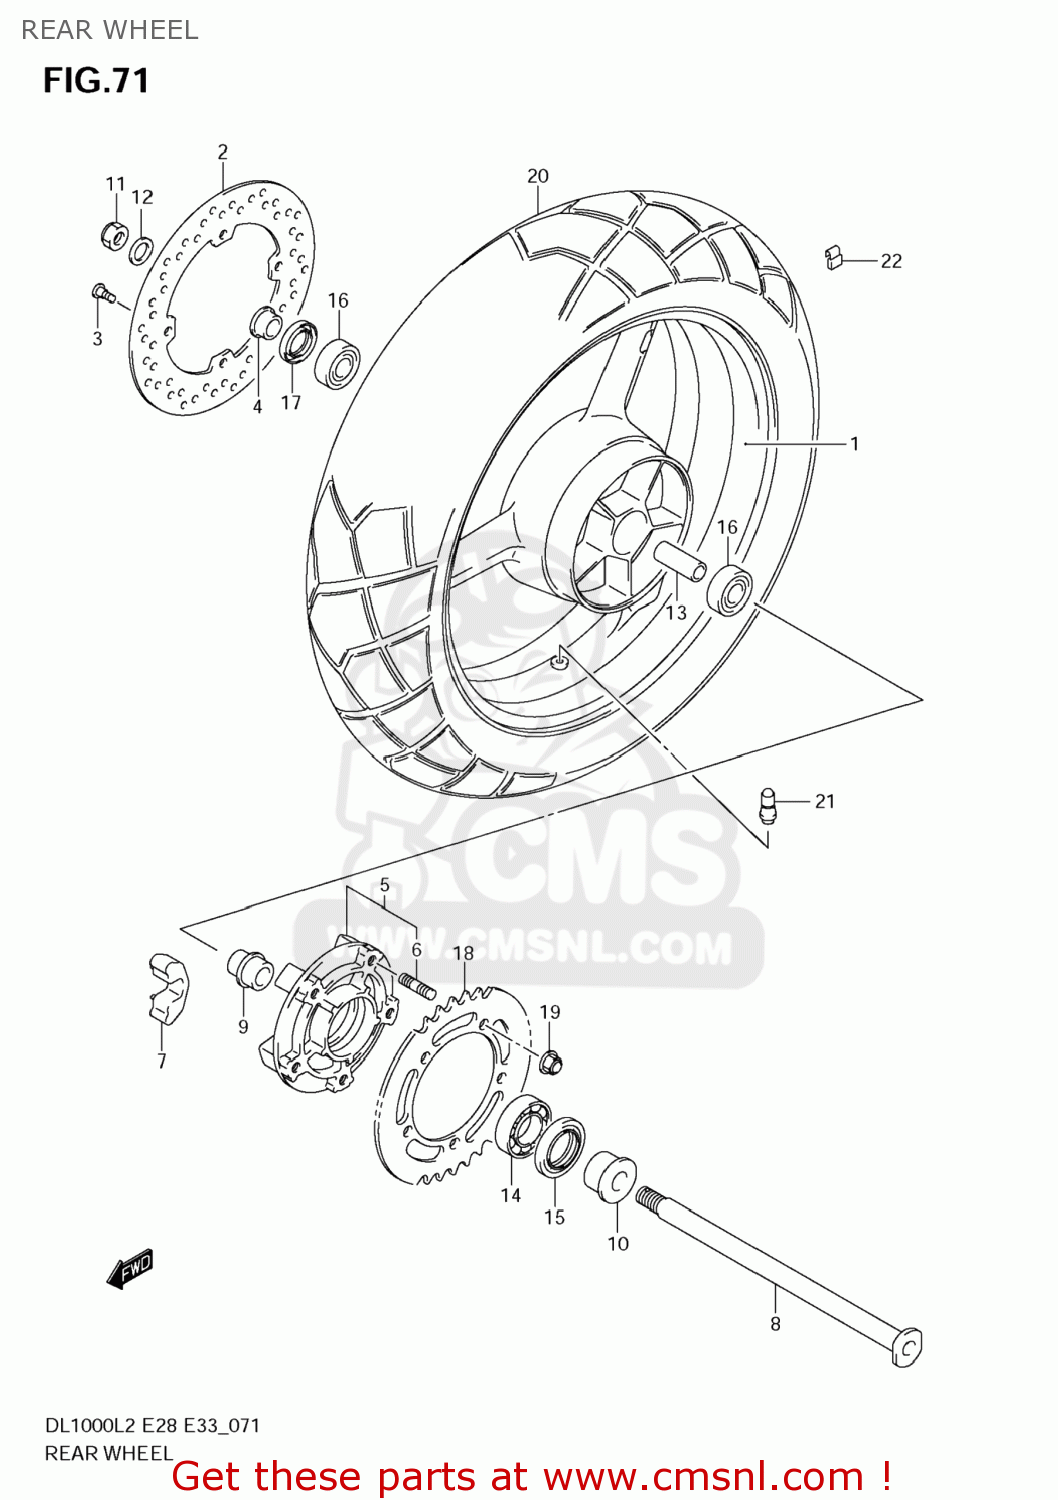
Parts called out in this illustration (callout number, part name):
1	WHEEL,RR(17M/CXMT4.00)
2	DISC,RR BRAKE
3	BOLT(8X21)
4	SPACER,RR AXLE,R
5	DRUM,RR SPROCKET
6	BOLT,STUD
7	ABSORBER,RR HUB SHOCK
8	AXLE,RR
9	RETAINER,RR SPROCKET DRUM
10	SPACER,FR AXLE
11	NUT
12	WASHER(19X32X3.2)
13	SPACER(20.8X27.2X124)
14	BEARING
15	SEAL,OIL(39X65X7)
16	BEARING
17	SEAL,OIL(28X47X7)
18	SPROCKET,RR(NT:41-525)
19	NUT
20	TIRE,REAR,150/
21	VALVE ASSY,WHEEL RIM(TR412)
22	WEIGHT,WHEEL BALANCE 10G
